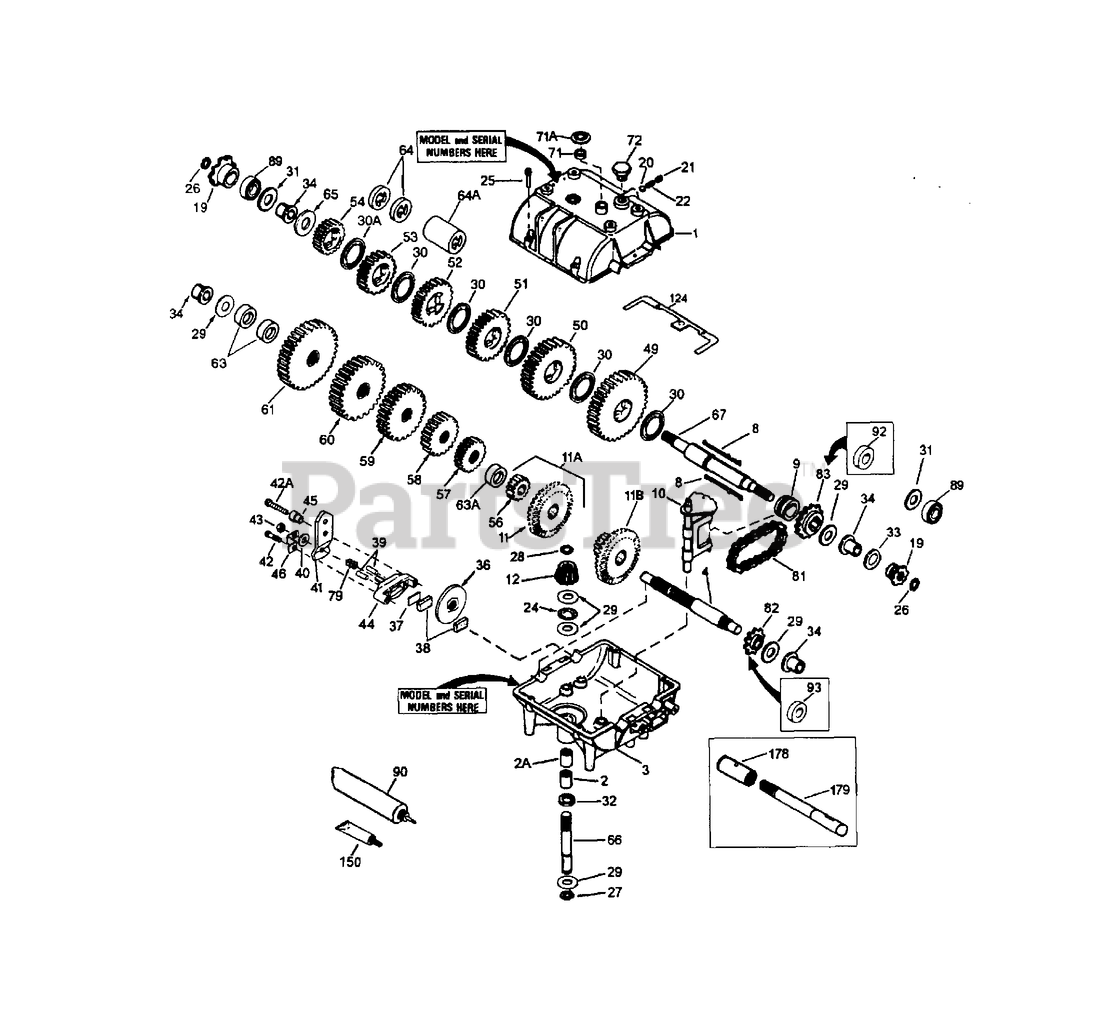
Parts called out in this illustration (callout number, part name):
1	Case, Transmisson
2	Needle Bearing Grease Spec
2A	BEARING, NEEDLE
3	Case, Transmission
8	Shift Key
9	COLLAR, SHIFT
10	Shift Rod & Fork
11	Gear, Bevel (42 teeth)
12	Bevel Pinion (14 teeth-steel)
20	Steel Ball, 5/16" dia.
21	SET SCREW, 3/8-16 X 3/8(1)
22	SPRING(1)
24	BEARING, THRUST(1)
25	Screw, Flanged Hex Hd Thread, 1/4-20 x 1-1/4"
27	RING, RETAINING
28	RING, RETAINING(1)
29	WASHER, THRUST(3)
30	WASHER, THRUST(4)
32	"O" RING(5)
34	BUSHING, FLANGED
49	Gear, Spur (37 teeth)
50	Gear, Spur (35 teeth)
51	Spur Gear (32 teeth-steel)
52	Gear, Spur (30 teeth)
53	Gear, Spur (25 teeth)
56	Spur Gear (12 teeth-steel)
57	Gear, Spur (15 teeth)
58	Spur Gear (18 teeth-steel)
59	Gear, Spur (20 teeth)
60	Gear, Spur (25 teeth)
65	WASHER, THRUST(1)
66	Input Shaft (3-11/16" long)
67	Shifter & Brake Shaft
71	SEAL, SQUARE CUT
72	Threaded Plug (Shipping only, not used)
81	CHAIN, ROLLER(NO. 41 CHAIN, 24 LINKS)(1)
82	SPROCKET(9 TEETH)(1)
83	Sprocket (18 teeth)
90	Grease (32 oz. bottle Bentonite grease)
150	Gasket Eliminator (Loctite #515)
178	Coupling (See page 26-27 for part number)
179	Connector Shaft (See page 26-27 for part number)
